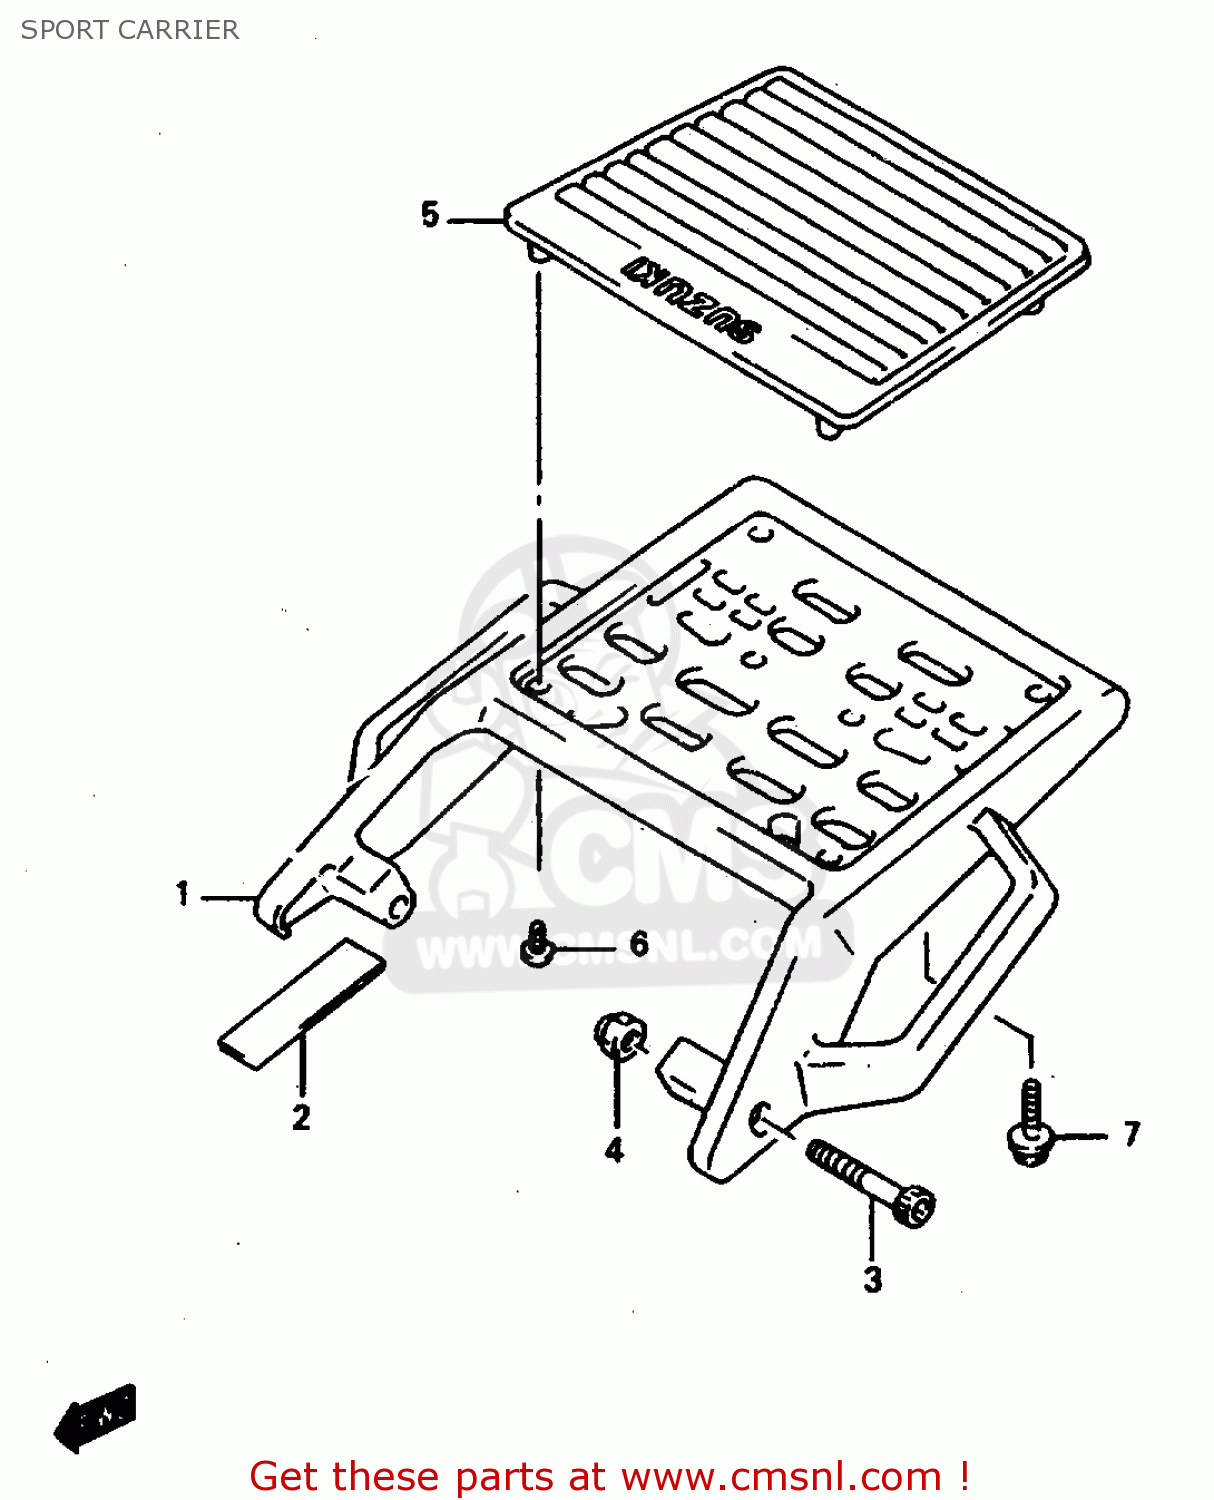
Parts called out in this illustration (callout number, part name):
1	CARRIER,SPORT
2	CUSHION,FR
3	BOLT
4	NUT
5	MAT,SP.CARRIER
6	SCREW(5X16)
7	BOLT
